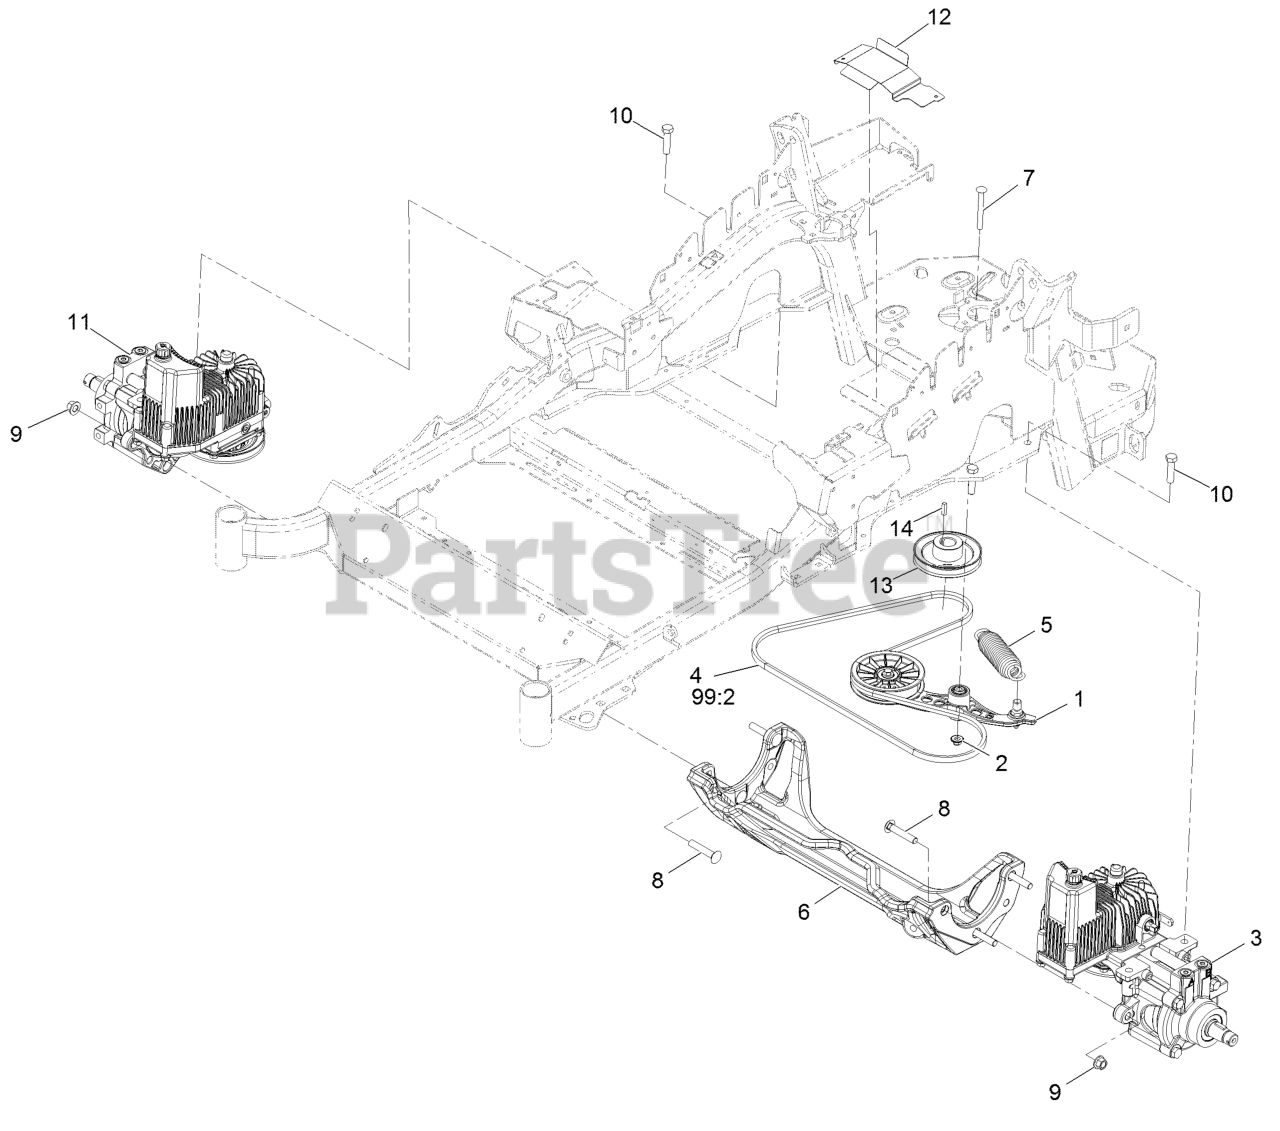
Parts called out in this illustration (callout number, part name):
1	PUMP IDLER ASM
2	Nut-Nyloc 3/8-16 Flg
3	LH HYDRO ASM (12CC NO FAN
4	BELT-V
5	SPRING-EXTENSION
6	CRADLE-HYDRO
7	BOLT-SHOULDER, CARRIAGE 3/8-16 X 3 1/2
8	SCREW-CARR
9	Nut-Lock 1/2-13
10	SCREW-HH
11	RH HYDRO ASM (12CC NO FAN
12	GUARD-BELT
13	SHEAVE-PUMP, DRIVE
99:2	BELT-V
